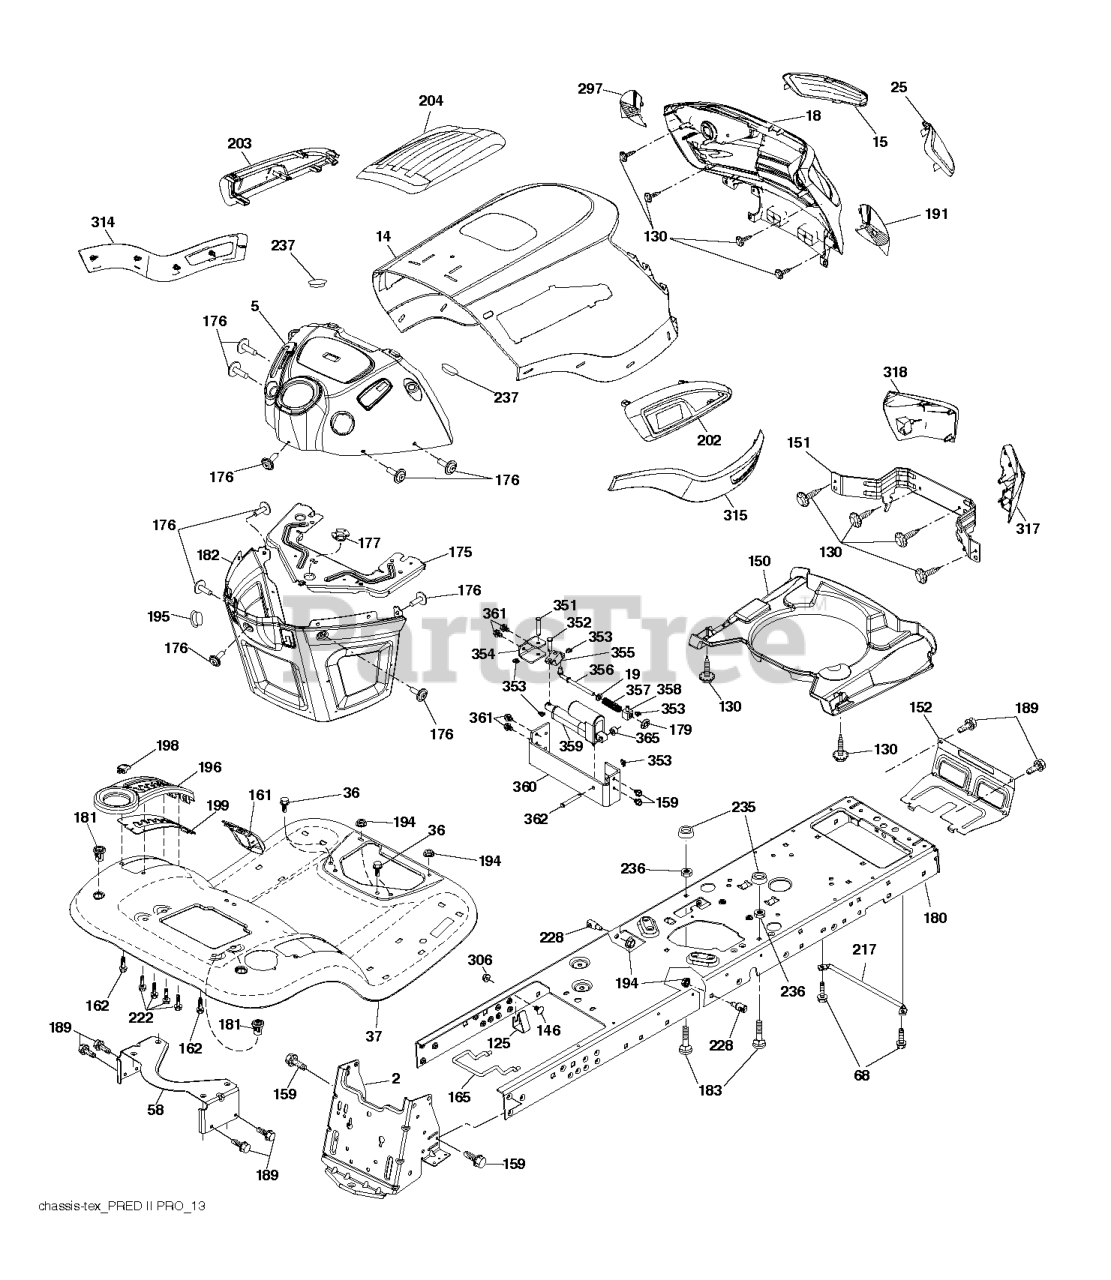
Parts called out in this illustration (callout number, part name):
2	DRAWBAR.STGT
5	DASHBOARD DASH.YT.PRED.REC.GA.
14	HOOD HOOD.GRILL.PREDII.YT/GT.Y
15	LENS.LH.PRED II.YT.CLR.SVC
18	GRILLE.PRED2.GT.PRO.REDMAX
19	WASHER
25	LENS.RH.PRED II.YT.CLR.SVC
36	SCREW 5/16"
37	FENDER FENDER PNT CONVERSION 4
58	BRKT.SUPPORT.FNDR/TANK
68	SCREW LT
125	CLIP.FUEL.LINE
130	SCREW.#10 X 0.750.BOS
146	BOLT.RDHD.SHT.SQNK.3/8-16X5/8
150	PREDATOR.YT.GT.HOOD.AIR DUCT
151	BRACKET.PIVOT.PREDATOR
152	SHIELD.BROWNING/DEBRIS
159	SCREW, 3/8-16X3/4
161	CONSOLE.FUEL.WINDOW.STGT.BLACK
162	SCREW.HI-LO.CONSOLE
165	SUPPORT.TANK.REAR.B/TE
175	PLATE.CROSSMEMBER.HUSQ
176	SCREW.#10-24X5/8.RN.QU
177	BUSHING STEERING
180	CHASSIS.TEX.BOLTED
181	BUSHING.MNT.FEND.CRGO.
182	DASH.LOWER.COMMON.12V.ADAPTOR
183	BOLT.5/16-18X1-1/4 FULL THD
189	SCREW
191	INSERT INSERT.REFLECTIVE.RH
194	NUT LOCK HEX FLANGE 5/16-18
195	PLUG.HOLE.DASH.LOWER.12V.BLK
196	CONSOLE ASM DECK LIFT BLACK
198	INDICATOR.DECK.LIFT.RED
199	PLATE DECK LIFT
202	VENT SIDE. HOOD. PREDATOR II.
203	VENT SIDE. HOOD. PREDATOR II.
204	VENT ASM.TOP.PRED GT PRO.428
217	ROD.PIVOT.HOOD
222	SCREW.1/4-20X5/8
228	STUD.FASTNER.W/ANTI-ROTATE
235	SPACER FENDER
236	NUT.CENTERLOCK.5/16-
237	PLUG.MOUNT.CARGO.BLK
297	INSERT INSERT.REFLECTIVE.LH
306	NUT LOCK FLG 3/8-16 UNC
314	TRIM SUBASM. PREDATOR II. YT/G
315	TRIM SUBASM. PREDATOR II. YT/G
317	BUMPER CORNER. PREDATOR II. GT
318	BUMPER CORNER. PREDATOR II. GT
351	PIN.CLEVIS.375X2.125
352	PIN.CLEVIS.(.375 X 1.25)
353	CLIP RETAINER
354	SUPPORT.BELLCRANK
355	BELLCRANK.PIVOT.LOCK.DIFF
356	LINK.LOCK.DIFF
357	SPRING.COMPRESSION
358	GUIDE.SWIVEL
359	ACTUATOR.ELECTRIC
360	BRACKET.ACUATOR
361	SCREW LT.3/8-46X5/8
362	PIN.CLEVIS.(.375 X 2.42)
365	SPACER.NYLON.75" X .4375
